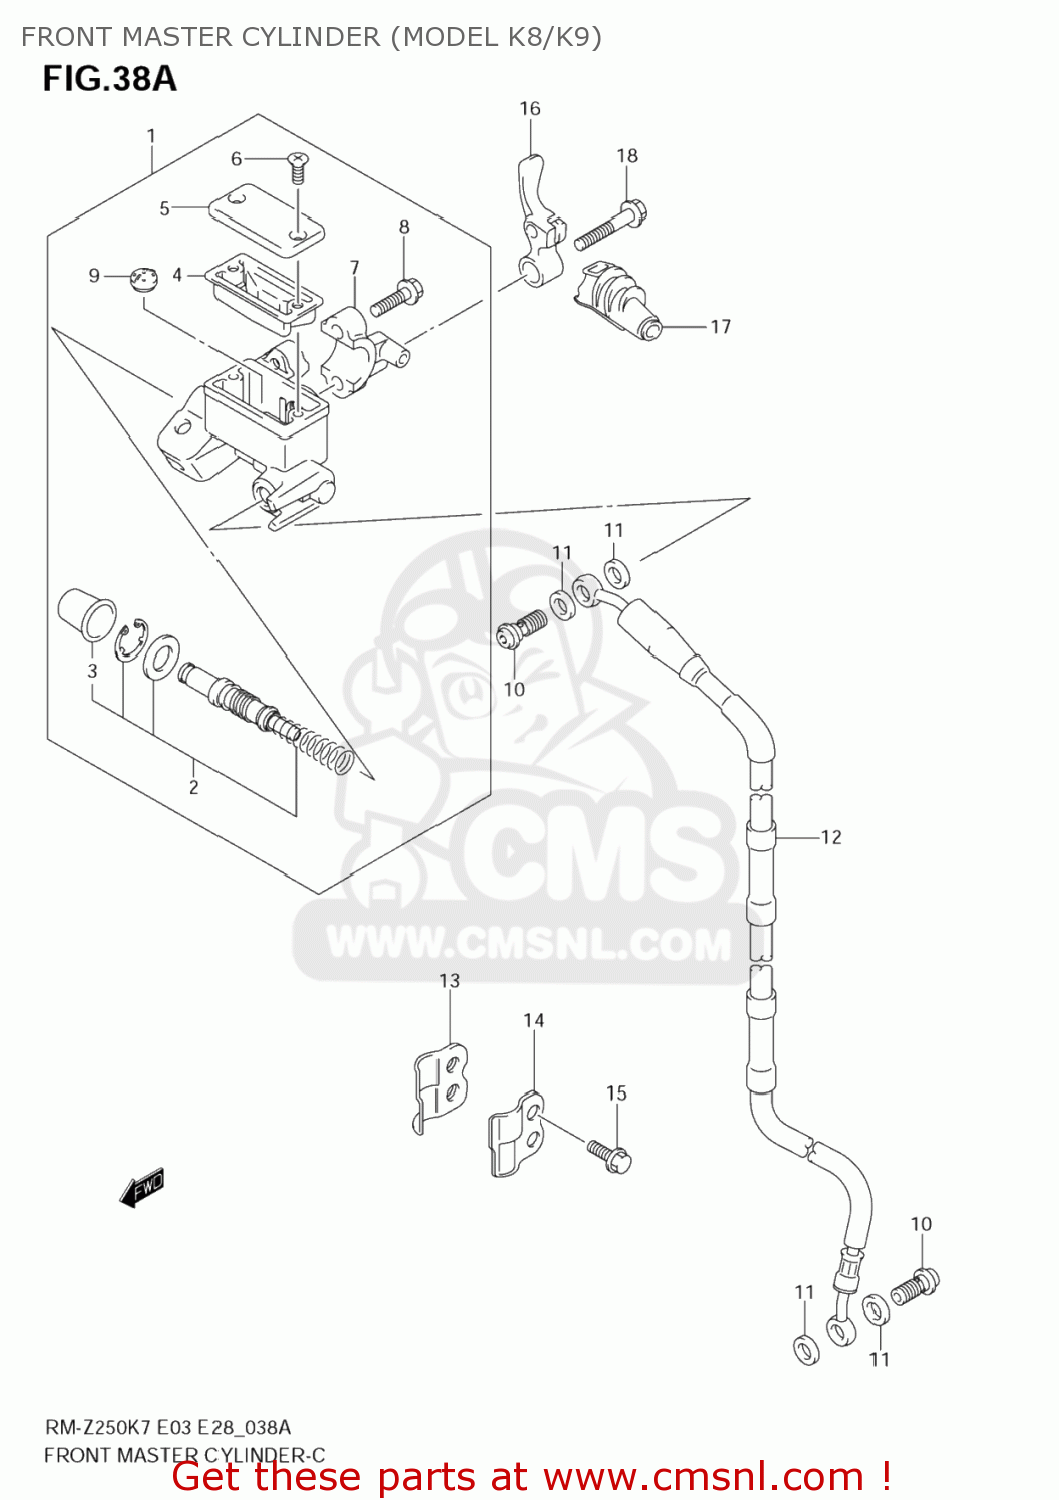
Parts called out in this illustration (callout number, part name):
1	CYLINDER ASSY,FR MASTER
2	PISTON & CUP SET
3	BOOT
4	DIAPHRAGM
5	CAP
6	SCREW
7	HOLDER
8	BOLT
9	SEPARATOR
10	BOLT UNION
11	WASHER(10X15X1.5)
12	HOSE,FR BRAKE
13	CLAMP,FR BRAKE HOSE
14	CLAMP,FR BRAKE HOSE
15	BOLT(6X16)
16	LEVER,MASTER CYLINDER HOLDER
17	COVER,MASTER CYL HOLDER LEVER
18	BOLT,MASTER CYLINDER HOLDER
